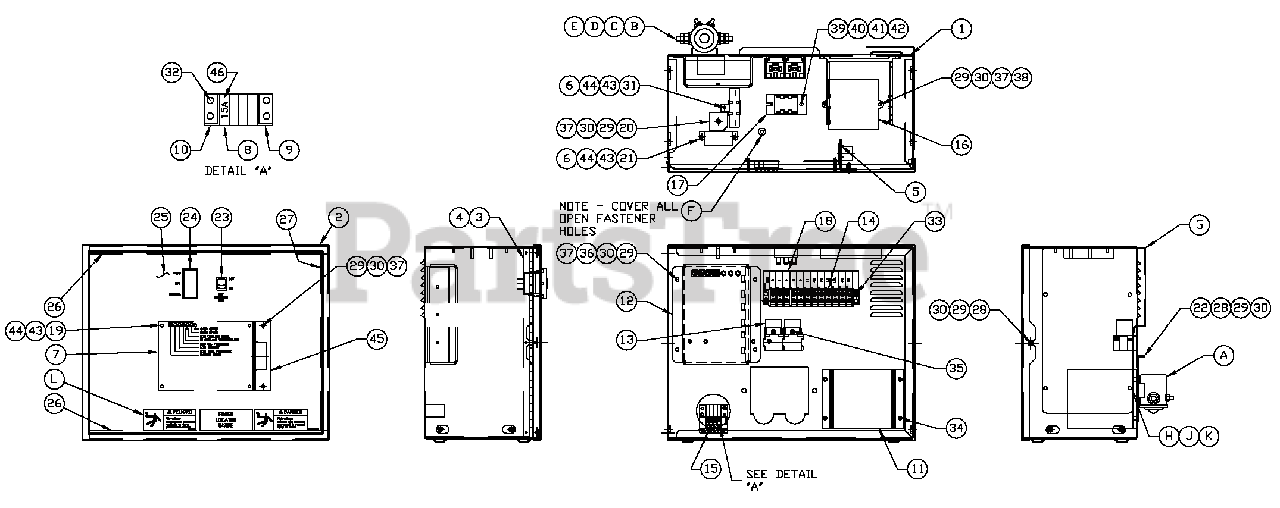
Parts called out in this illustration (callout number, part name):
1	ENCL HSB CONTROL PANEL
2	COVER CONTROL PANEL
3	HINGE CONTINUOUS H-PANEL
4	RIVET POP .125 X .275 SS
5	SCREW PPPH HI-LO #4-24 X 3/8
6	WASHER FLAT M3
7	ASSY PCB R-200 3600 RPM
8	HOLDER, FUSE WICKMANN 178.6150
9	ADPTR,RH SIDE WICKMAN 178.6191
10	ADPTR,LH SIDE WICKMAN 178.6192
11	ASSY PCB 2AMP 12V UL BATT CHGR
12	ASSY VOLTAGE REGULATOR 60HZ
13	RELAY, 12VDC C FORM W/DIODE
14	BLOCK TERM 20A 12 X 6 X 1100V
15	DECAL CPL CONTROL PANEL FUSES
16	ASSY PCB BOSCH GOV DRIVER
17	ASSY PCB SCR BRIDGE
18	DECAL CPL 3.9L TB1
19	SPACER 9.5H 3.2 ID
20	DIO BRIDGE 25A 600V
21	CIRCT BRK 7 X 1 ETA 46-500-P
22	PLATE,HARNESS CLAMP
23	SWITCH RKR DPST 125V SPD
24	SWITCH RKR DPDT ON-OFF-ON
25	DECAL, CONTROL HSB
26	SEAL COVER 3.18X12.7X382
27	SEAL COVER 3.18X12.7X283
28	SCREW HHPM M5-0.8 X 12
29	WASHER FLAT M5
30	WASHER LOCK M5
31	RES WW 15R 5% 25W QK CONN
32	SCREW PHTT M3.5-0.6 X 10
33	SCREW PHTT M3.5-0.6 X 16
34	SCREW PHTT M4-0.7 X 12 ZYC
35	SCREW PHTT M4-0.7 X 10 ZYC
36	SCREW PPHM M5-0.8 X 12 ZNC
37	NUT HEX M5-0.8 G8 CLEAR ZINC
38	SCREW PPHM M5-0.8 X 30 SS
39	SCREW PPHM M4-0.7 X 16
40	WASHER FLAT M4
41	WASHER LOCK #8-M4
42	NUT HEX M4-0.7 G8 YEL CHR
43	WASHER LOCK M3
44	NUT HEX M3-0.5 G8 YEL CHR
45	SUPPORT ANGLE PCB
46	FUSE ATO TYPE 15 AMP (BLUE)
47	HARN 3600RPM R200 CONTROL PNL
A	RELAY SOLENOID 12VDC PNL MNT
B	SCREW HHC 1/4-20 X 3/4 G5
C	WASHER FLAT 1/4-M6 ZINC
D	WASHER LOCK M6-1/4
E	NUT HEX 1/4-20 STEEL
F	SEAL WEATHER .45"DIA
G	COVER CONTROL PANEL SIDE
H	SCREW PPHM M5-0.8 X 12 ZNC
J	WASHER LOCK M5
K	WASHER FLAT M5
L	DANGER HIGH VOLTAGE (SPANISH)
